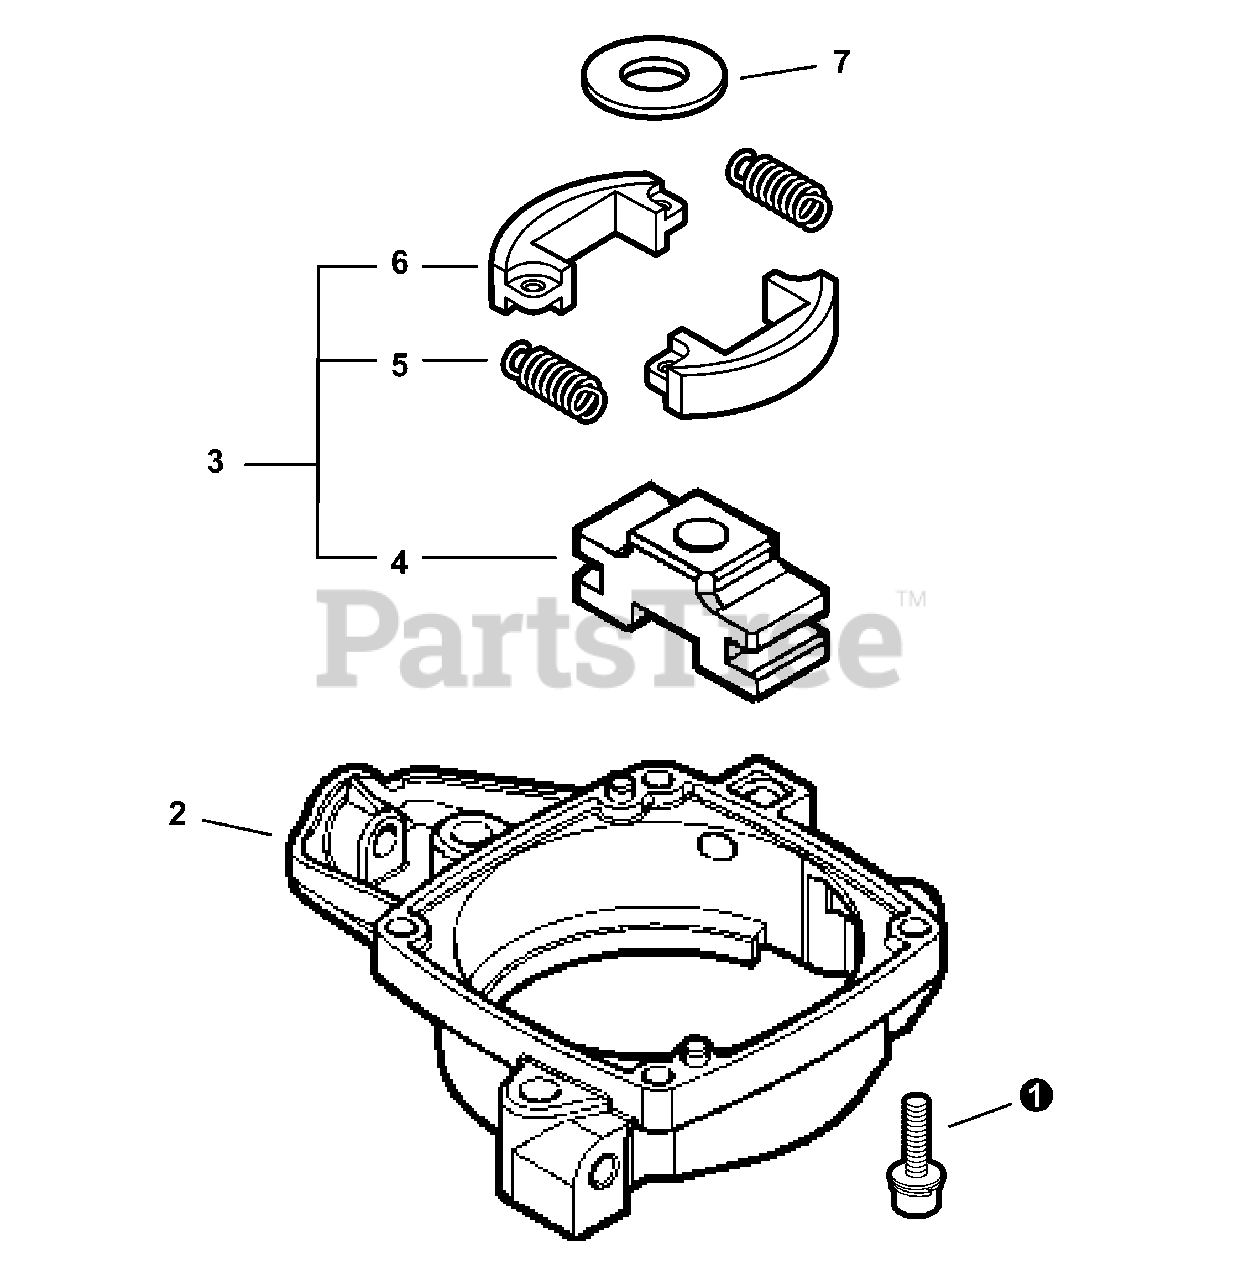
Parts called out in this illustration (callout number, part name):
1	SCREW - 4×16
2	CASE, CLUTCH
3	CLUTCH ASSY
4	HUB, CLUTCH
5	SPRING, CLUTCH
6	SHOE, CLUTCH
7	WASHER - 8
